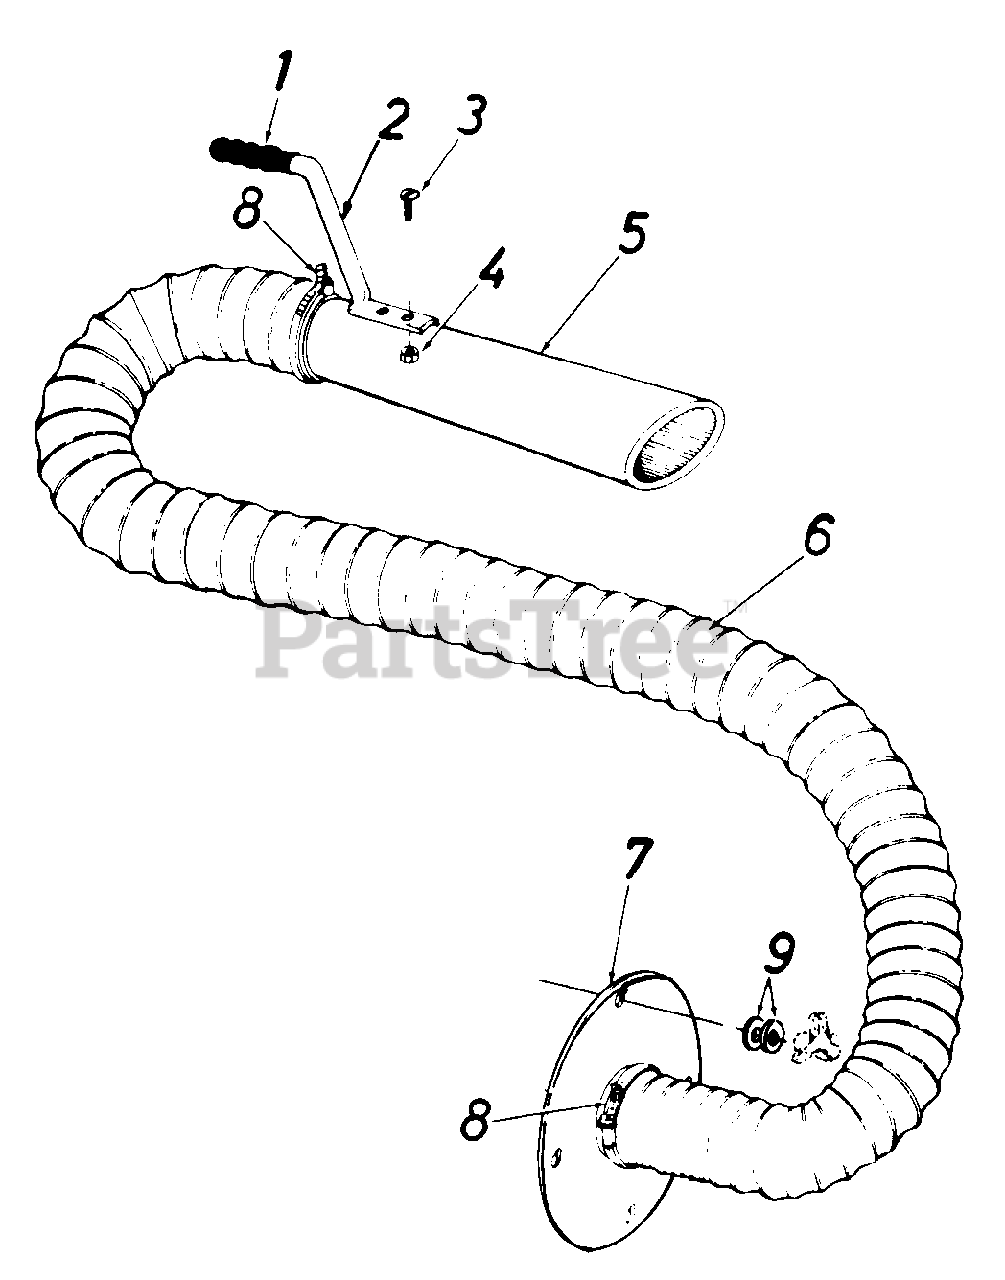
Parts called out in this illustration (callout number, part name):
1	GRIP-BLACK
2	HANDLE-HOSE NOZ LONG
3	SCREW-TRUSS SEMS #10-24 X .50
5	NOZZLE-HOSE
6	HOSE-4IN DIA X 10FT
9	WASHER-FL-.312 X 1.125 X .125
